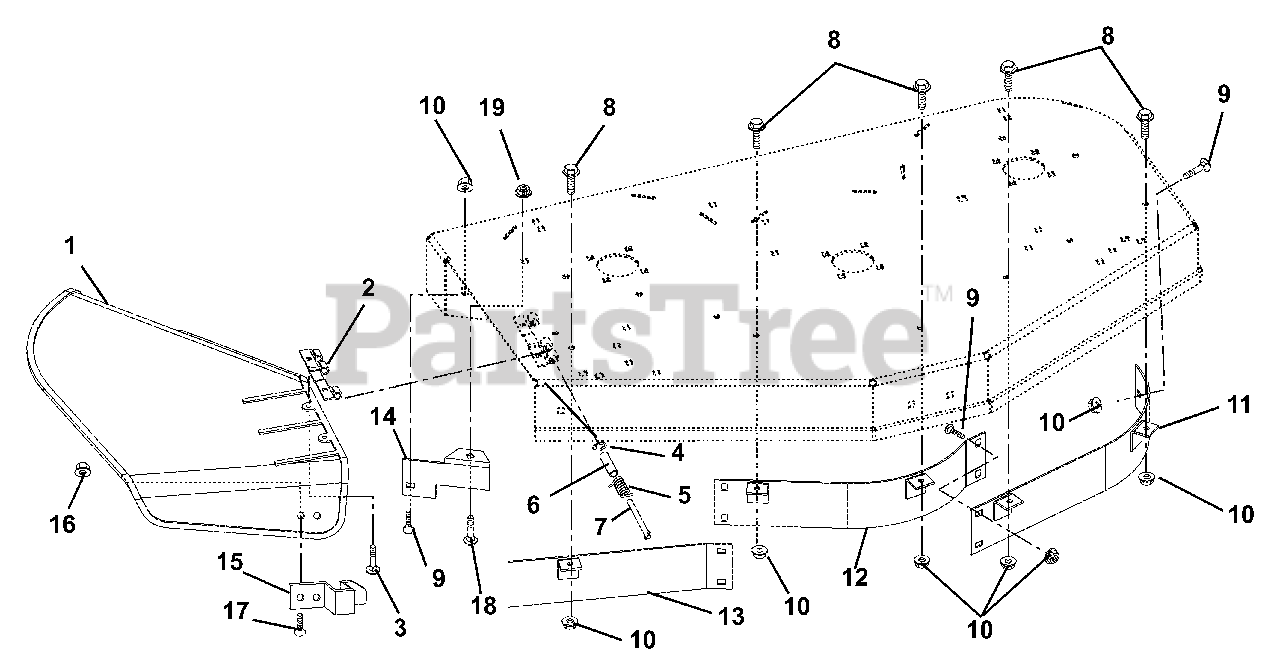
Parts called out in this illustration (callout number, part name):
1	Deflector, Chute
2	Hinge, Plate
3	Bolt, Round Head Square Neck .25-20 x .75 Grade 5
4	Ring, Retaining External .312 x .025
5	Spring, Torsion .095 x .50 x 1.00
6	Bushing, Sleeve
8	Bolt, Serrated Hex Flange Washer Head .312-18 x .75
9	Bolt, Round Head Square Neck .31-18 x .75
10	Nut-5/16-18 Flange Nyloc
11	Weldment, Upper Left Baffle-40"
12	Weldment, Upper Center Baffle-40"
13	Weldment, Upper Right Baffle-40"
14	Deflector, 40"
15	Flat Spring
16	Nut, Locking Top Flange .25-20
17	Bolt, Round Head Square Neck .25-20 x .50 Grade 5
18	Bolt, Round Head Square Neck .38-16 x 1.00 Grade 5
19	Nut-3/8-16 Flange Nylon
